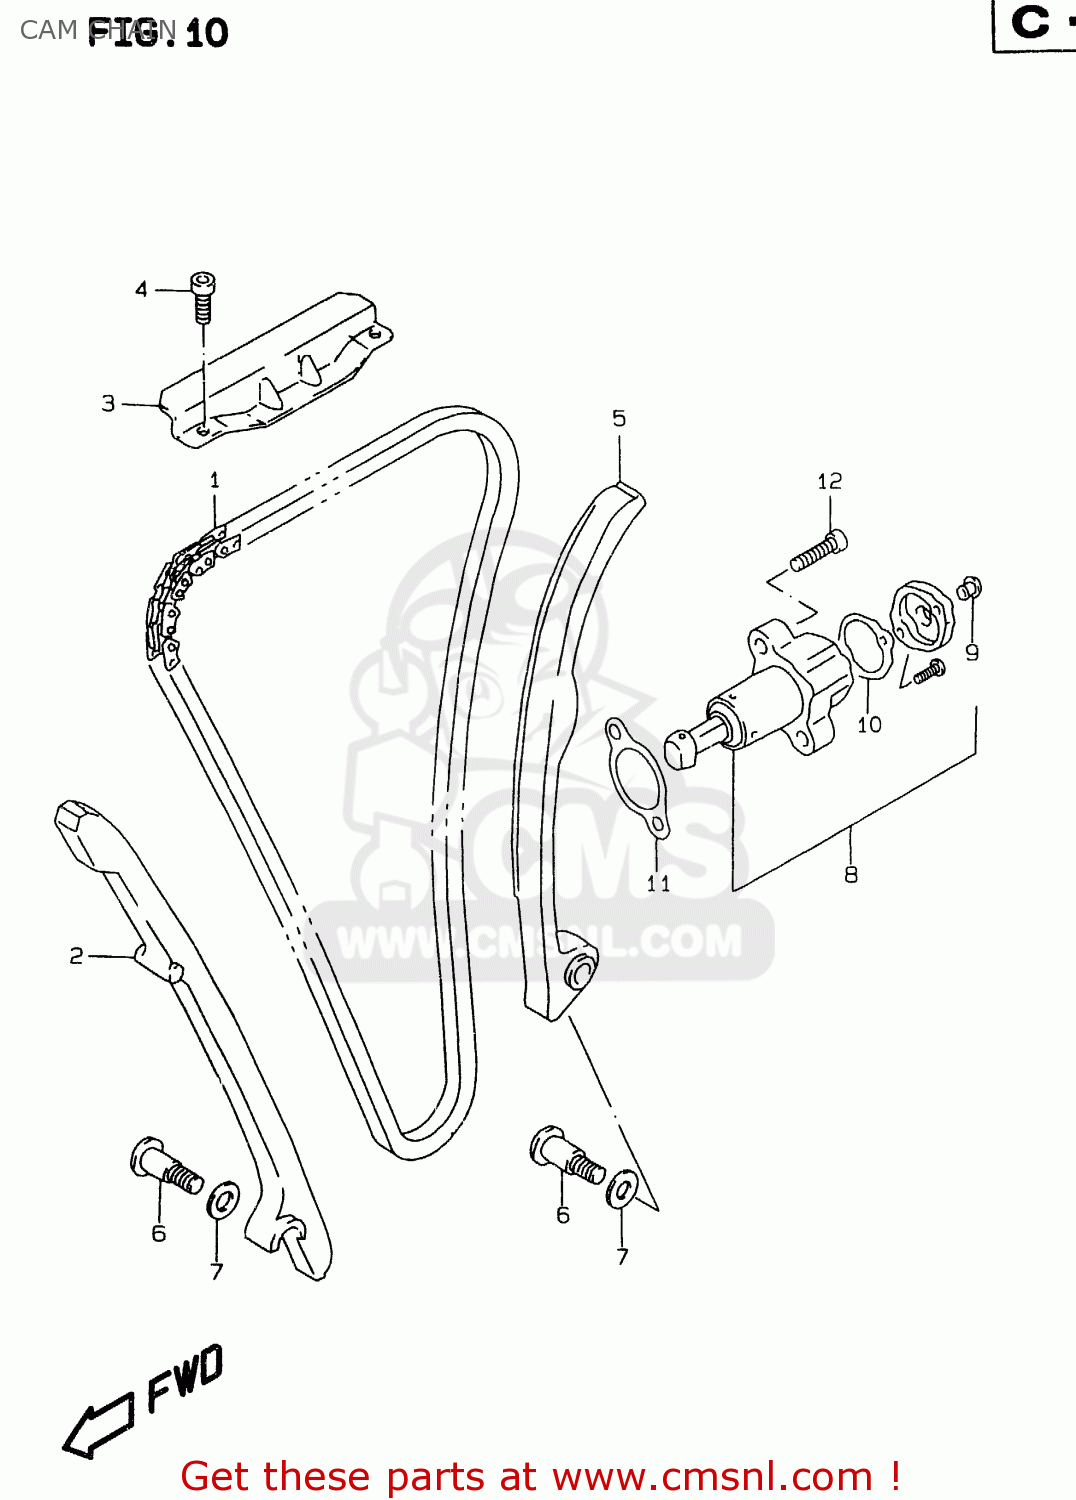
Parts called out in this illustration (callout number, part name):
1	CHAIN,CAMSHAFT DRIVE
2	GUIDE,CAM CHAIN NO.1
3	GUIDE,CAM CHAIN NO.2
4	BOLT,STRANGER
5	TENSIONER,CAM CHAIN
6	BOLT,CAM CHAIN TENSIONER/GUIDE
7	WASHER
8	ADJUSTER ASSY,TENSIONER
9	PLUG,ADJUSTER
10	GASKET,ADJUSTER CAP (NAS)
11	GASKET,TENSIONER ADJUSTER (NAS)
12	BOLT,CL.COVER
